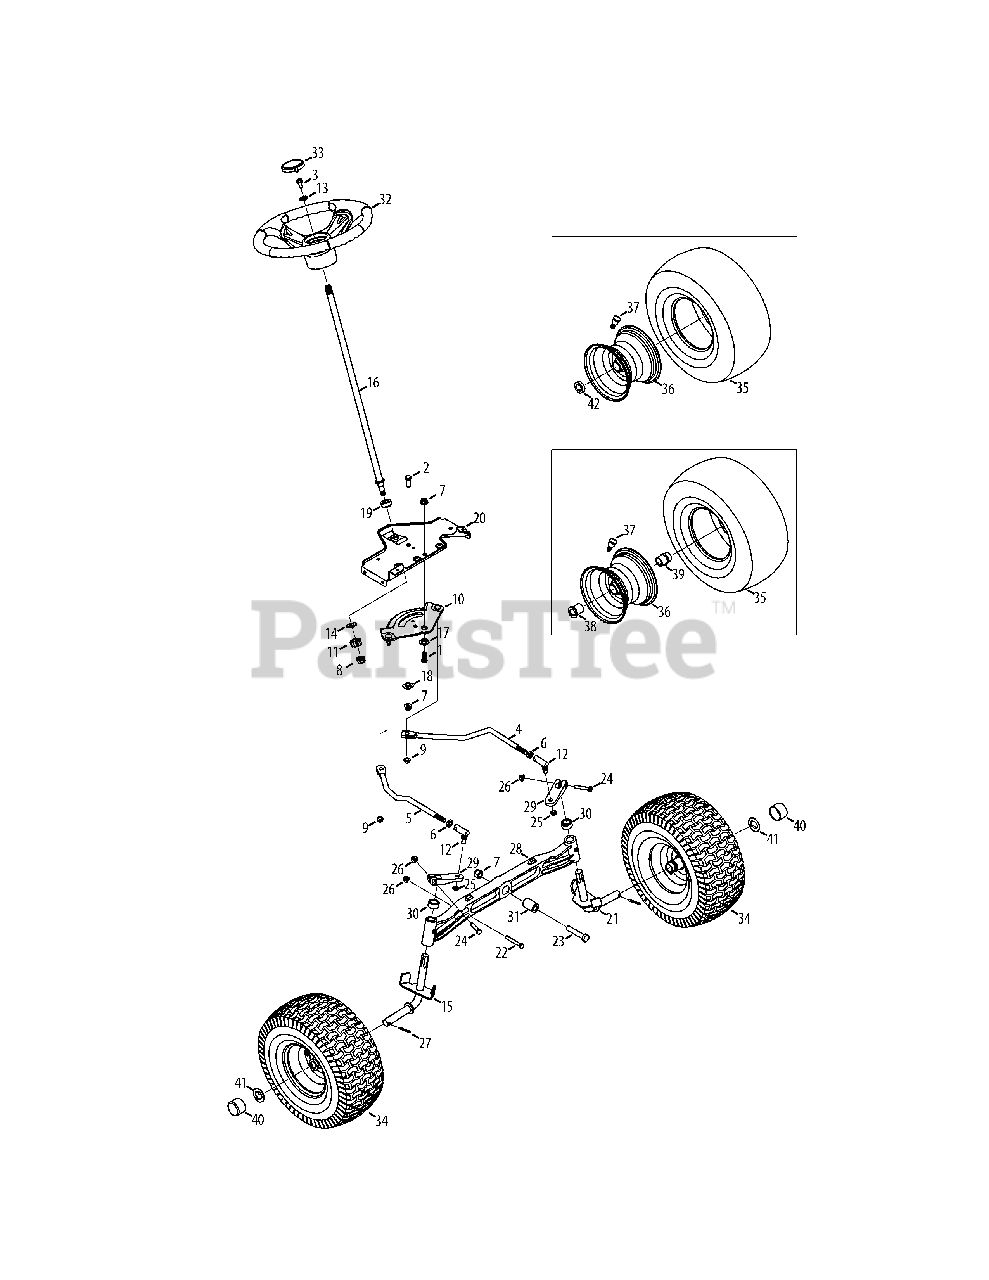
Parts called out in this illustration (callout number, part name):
1	Hex Screw, 3/8-16, 1.00, Gr5, Spec
2	Hex Screw, 3/8-16, 1.00, Gr5, Std
3	Hex Screw, 5/16-18, 1.00, Gr5, Lock
4	Link, Drag LH
5	Link, Drag RH
6	Nut, Jam, 7/16-20, Gr2
7	Nut, Flange Lock, 3/8-16, Grf,
8	Nut, Flange Lock, 7/16-20, Grb, Lock
9	Nut, Flange Lock, 5/16-18, Gr5, Sd Lk
10	Gear, Steering, 11/90 Ratio
11	Gear, Pinion, Steering
12	Ball Joint, 7/16-20, Lock
13	Washer, Flat, .406 x .875 x .105
14	Washer, Flat, .51 x 1.12 x .06
15	Axle Ass’y, RH .750 Dia (46" Deck)
16	Shaft, Steering, .625 OD x 24.25
17	Spacer, Shoulder, .385x 1.25 x .3025
18	Spacer, .38 x 1.375, Special, 46" Only
19	Bearing, Flange, Hex 5/8 Pm
20	Bracket, Support, Steering
20	Screw .750 5/16-18
21	Axle Ass’y, LH .750 Dia (46" Deck)
22	Hex Screw, 5/16-18, 2.25, Gr5, Std
23	Hex Screw, 3/8-16, 2.50, Gr5, Std
24	Hex Screw, 5/16-18, 1.75, Gr5, Std
25	Nut, Hex Lock, 3/8-24, Grb
26	Nut, Flange Lock, 5/16-18, Grf
27	Pin, Cotter, 5/32, 1.25
28	Axle, Pivot Bar, Cast
29	Steering, Block
30	Spacer, .71 ID x .125 OD x .56
31	Spacer, .385 x 1.00 x 1.5075
32	Steering Wheel, Soft Grip
33	Cap, Steering
34	Wheel Assembly
35	Tire, 15 x 6 x 6
36	Rim Assembly, Flange Bearings, 46"
37	Tubeless Air Valve
38	Flange Bearing, .760 x 1.00 x 1.20
39	Flange Bearing, .760 ID w/ Fitting
40	Cap, Bumper, 46"
41	Washer, Flat, .350 x 1.559 x .062, 46"
42	Bearing, Ball, .750 x 1.750, 38" & 42"
